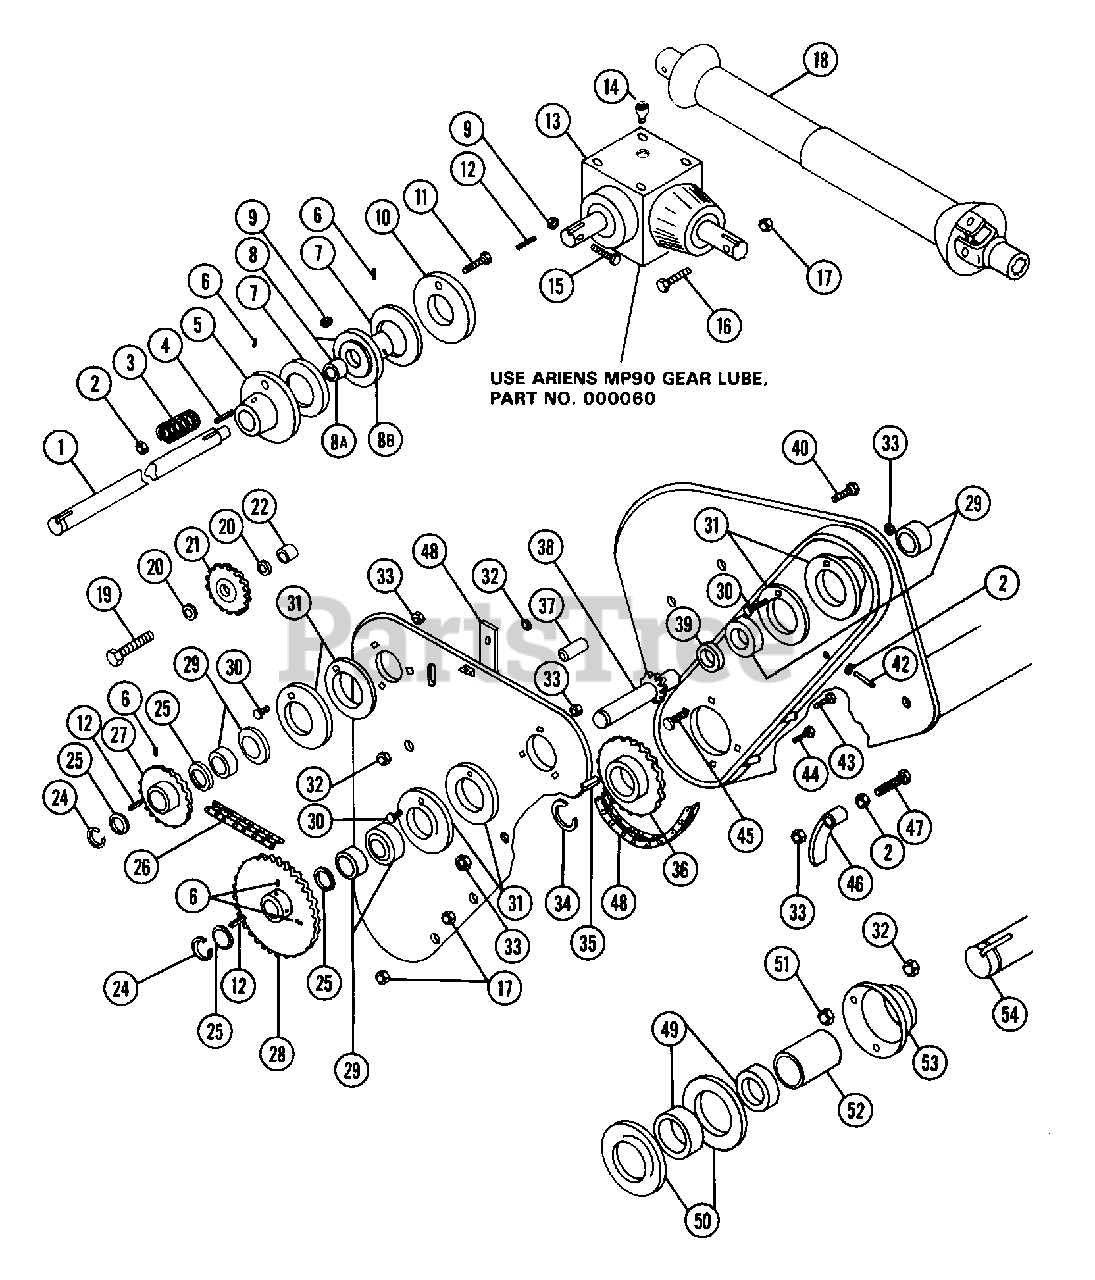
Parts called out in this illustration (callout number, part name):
1	DRIVE SHAFT
2	NUT-HEX .312-18
3	SG-COMP .135X.66X.75 WLD210
4	KEY-SQ .25 X 1.50 X .25 SAE
5	HUB-END PLATE
6	SCR-SET .32-18X.50 SKH
7	CLUTCH DISC
8	HUB ASSEMBLY
8A	OILITE BEARING
9	NUT-LK TOP .250-20 PL
10	PRESSURE PLATE
11	BLT-HEX .31-18X2.75 GR5
12	KEY-SQ .25X1.0X.25 SAE 8630
13	GEAR BOX ASSEMBLY
14	PIPE PLUG 1/4 NPT SQ HD PLASTI
15	BLT-HEX .25-20X2.50 PL GR2
16	BLT-HEX .38-16X2.00 PL GR5
17	NUT-LK TOP .375-16 GR C YWZC
18	UNIVERSAL DRIVE SHAFT
19	BLT-HEX .50-13X2.75 PL GR5
20	WSHR-FL-STL .505X1.000X.062
21	IDLER SPROCKET
22	SPACER-IDLER
24	RG-RTNG-EXT 1.00X.042
25	WSHR-FL-STL 1.015X1.500X.134
26	ROLLER CHAIN
27	SPROCKET 11 T
28	SPROCKET 40 T
29	BRG-BALL 1.0X2.047X.59
30	BLT-RDHDSQNK.31-18X.75GR5SHTPL
31	FLANGETTE
32	NUT-LK-CROWN .50-13 GR C PL
33	NUT-LK-TOP .312-18 GR C PL
34	RG-RTNG-EXT 1.500X.050
35	KEY-SQ .38X1.00X.375 SAE 1035
36	DRIVEN SPROCKET
37	TUBE .512 X .747 X 2.00
38	SPROCKET SHAFT
39	SPACER 1.050X1.312X.410
40	BLT-HEX .50-13X3.00 PL GR2
42	SCR-SET .32-18X2.00 SKHCUP
43	BLT=RDHDSQNK .38-16X2.75 GR2PL
44	CARRIAGE BOLT-SPECIAL
45	BLT-RDHDSQNK .50-13X1.50 PL
46	CHAIN TIGHTNER
47	BLT-HEX .31-18X2.75 GR2
48	DRIVE CHAIN
49	BRG-BALL 1.50X80MMX1.7
50	FLANGETTE-4 HOLE
51	NUT .50-13 PL
52	TUBE-TINE
53	CAP-BEARING GUARD
54	TINE SHAFT
